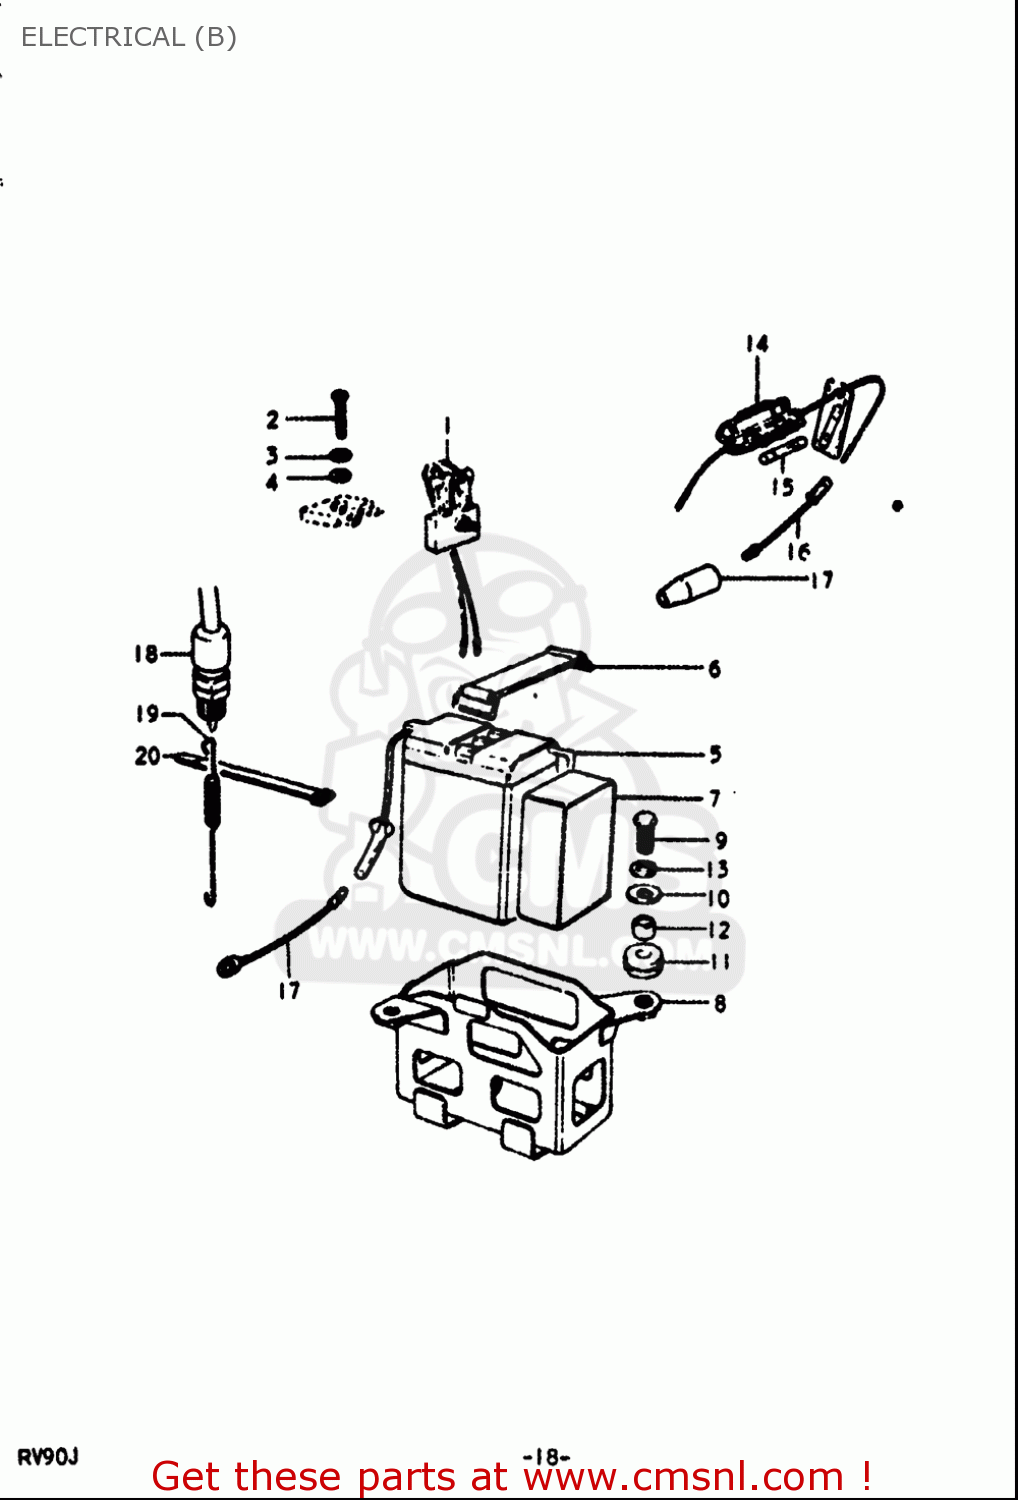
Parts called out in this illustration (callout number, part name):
1	RECTIFIER ASSY
2	SCREW
3	WASHER,LOCK
4	WASHER
5	BATTERY ASSEMBLY (6V)
6	BAND
9	BOLT
10	WASHER(6.5X20X1.2)
11	CUSHION
12	SPACER,6.5X9X7
13	WASHER,LOCK
14	CASE ASSY,FUSE
15	FUSE(15A)
16	LEAD WIRE
18	SWITCH,BRAKE LAMP
19	SPRING
20	CLAMP
